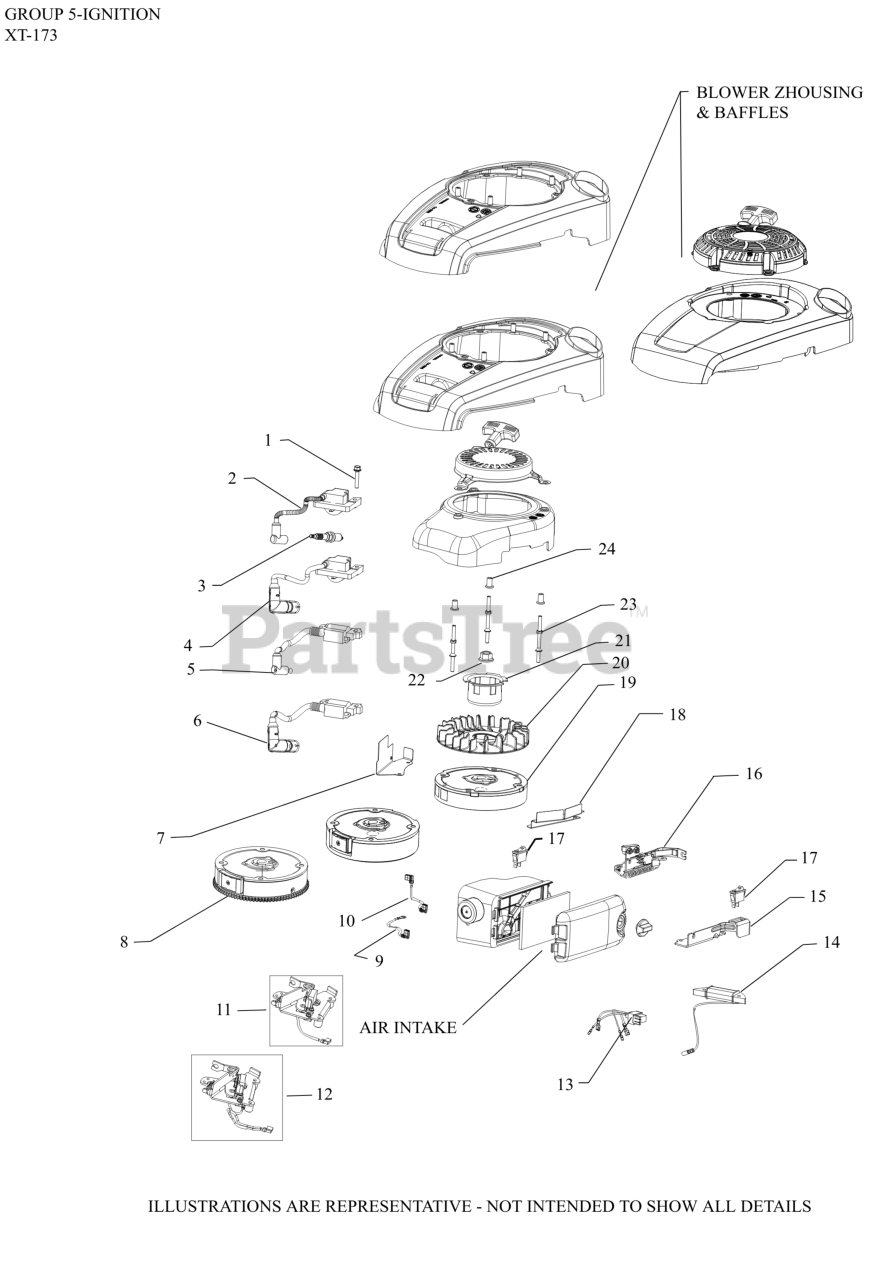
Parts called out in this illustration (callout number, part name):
3	SPARK PLUG
4	MODULE, IGNITION (ALUM. W/RFI)
16	BRAKE ASSEMBLY, CARB SIDE
20	FAN, FLYWHEEL-(#1715706S)
21	CUP, DRIVE - (#1410905S)
22	NUT, FLYWHEEL (W/SERRATIONS)
NI	FLYWHEEL ASSEMBLY (ALUMINUM)
